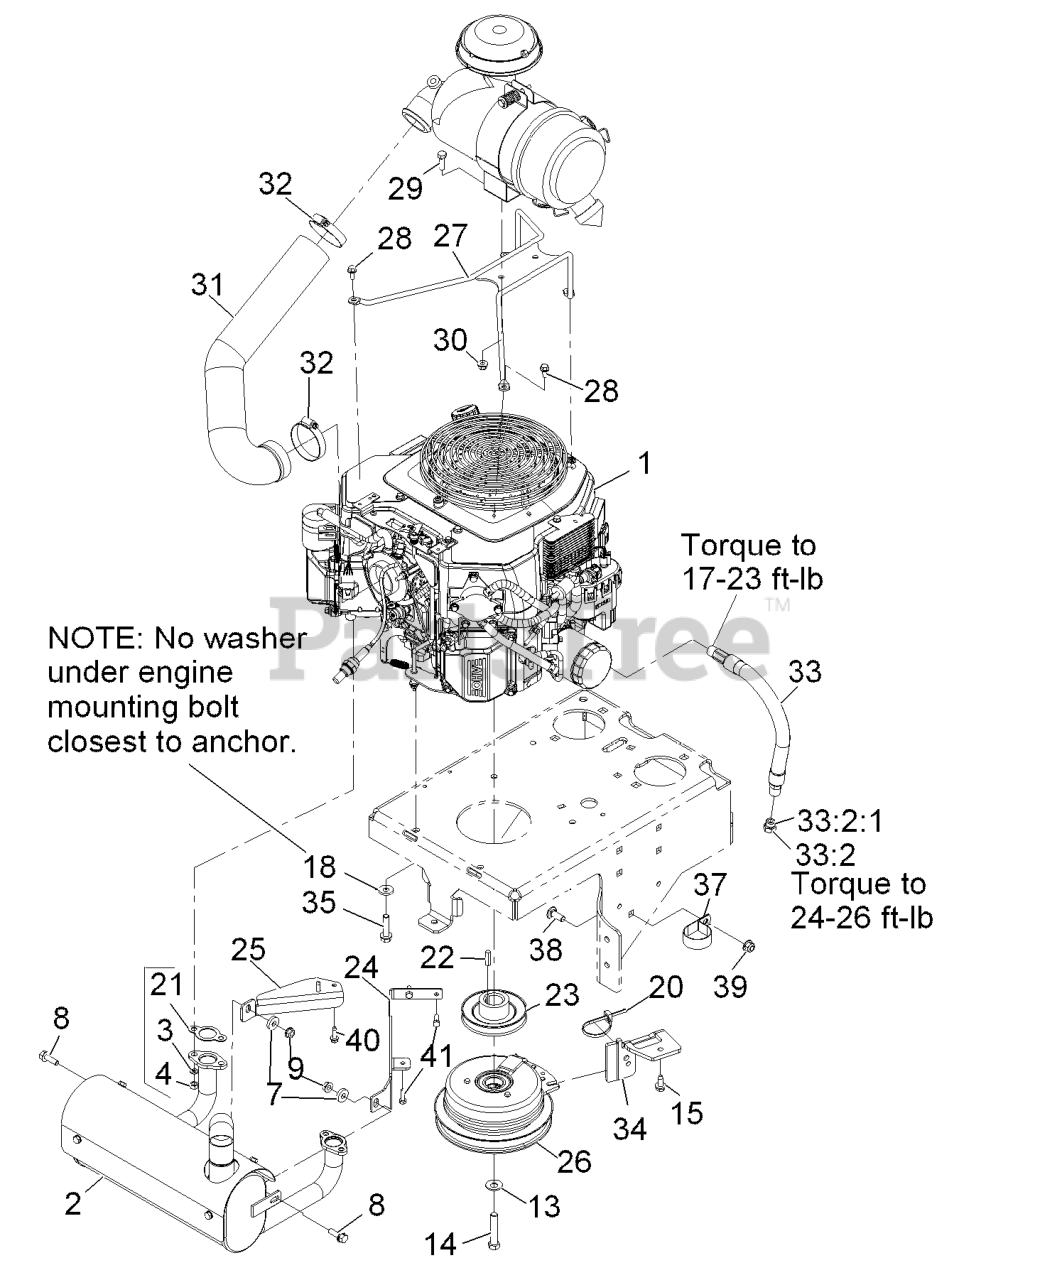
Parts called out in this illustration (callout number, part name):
1	Engine-Kohler 25hp Efi
3	WASHER-LOCK
8	SCREW-HHF
13	WASHER-SPRING
14	SCREW-HH
15	Screw-HWH 5/16-18 X 3/4 Tf
18	WASHER-BELLEVILLE
20	TIE-CABLE
21	GASKET-EXHAUST
25	BRACKET-MUFFLER, RH
26	CLUTCH-175 FT-LB, 1.125 B
28	SCREW-HHF
29	SCREW-HH
30	NUT-HF, NI
31	HOSE-INTAKE, AIR
32	CLAMP-HOSE
33	OIL DRAIN HOSE ASM
33:2	PLUG-HH
33:2:1	O-RING
34	BRACKET-ANCHOR, CLUTCH
35	SCREW-HWH
37	CLAMP-R
38	SCREW-CARR
39	NUT-HF, NI
40	SCREW-HH M6-1 X 20Mm W/Patch
41	SCREW-HH M6-1 X 20Mm W/Patch
